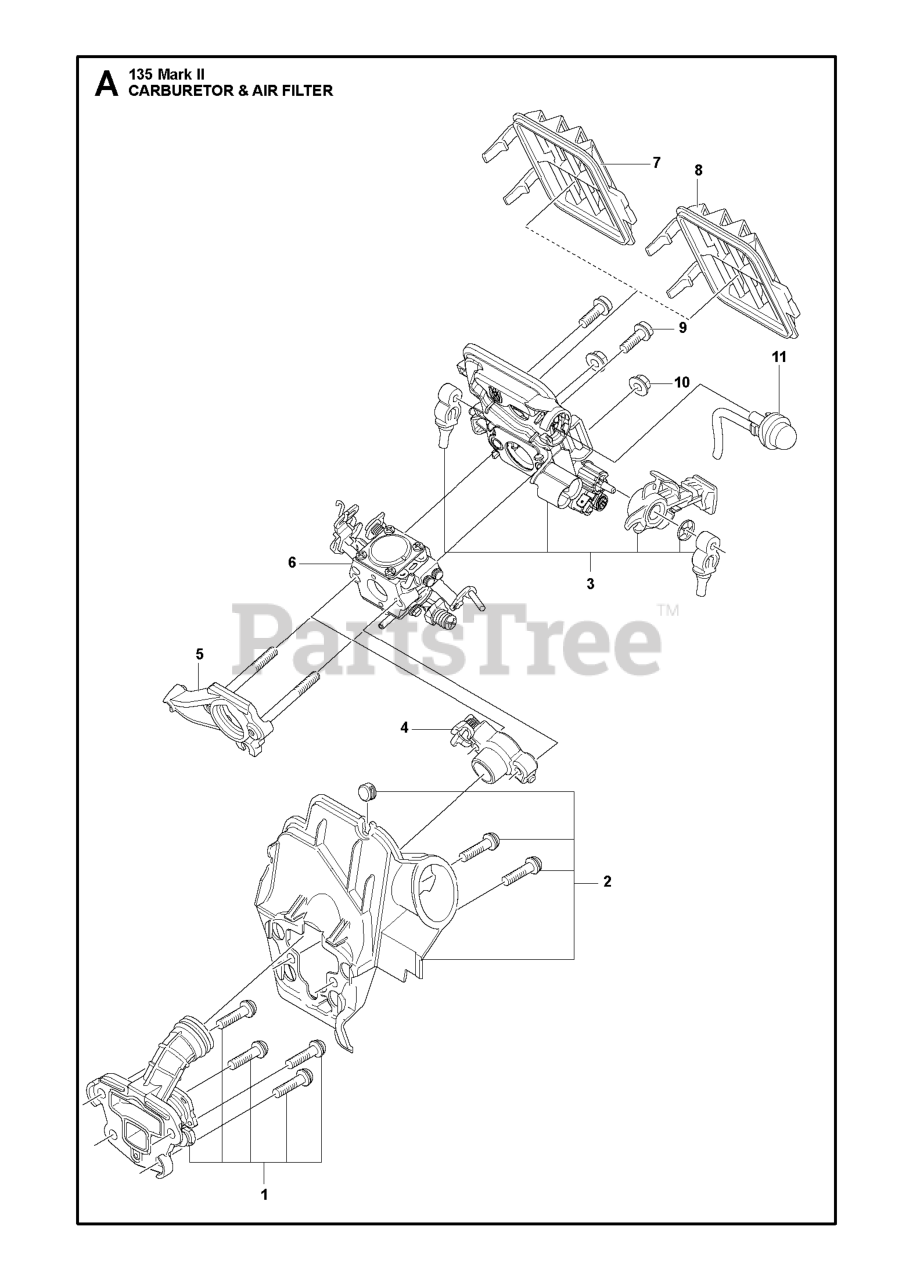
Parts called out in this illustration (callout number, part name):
1	INLET INTAKE BOOT
2	SERVICE KIT INSULATION WALL
3	SERVICE KIT FILTER HOLDER
4	VALVE ASSY AIR 130 CHAINSAW
5	FLANGE ASSY CARB H130 OVERMOLD
6	CARBURETOR
7	AIR FILTER MESH
8	AIR FILTER NON WOVEN
11	AIR PURGE BUBBLE
